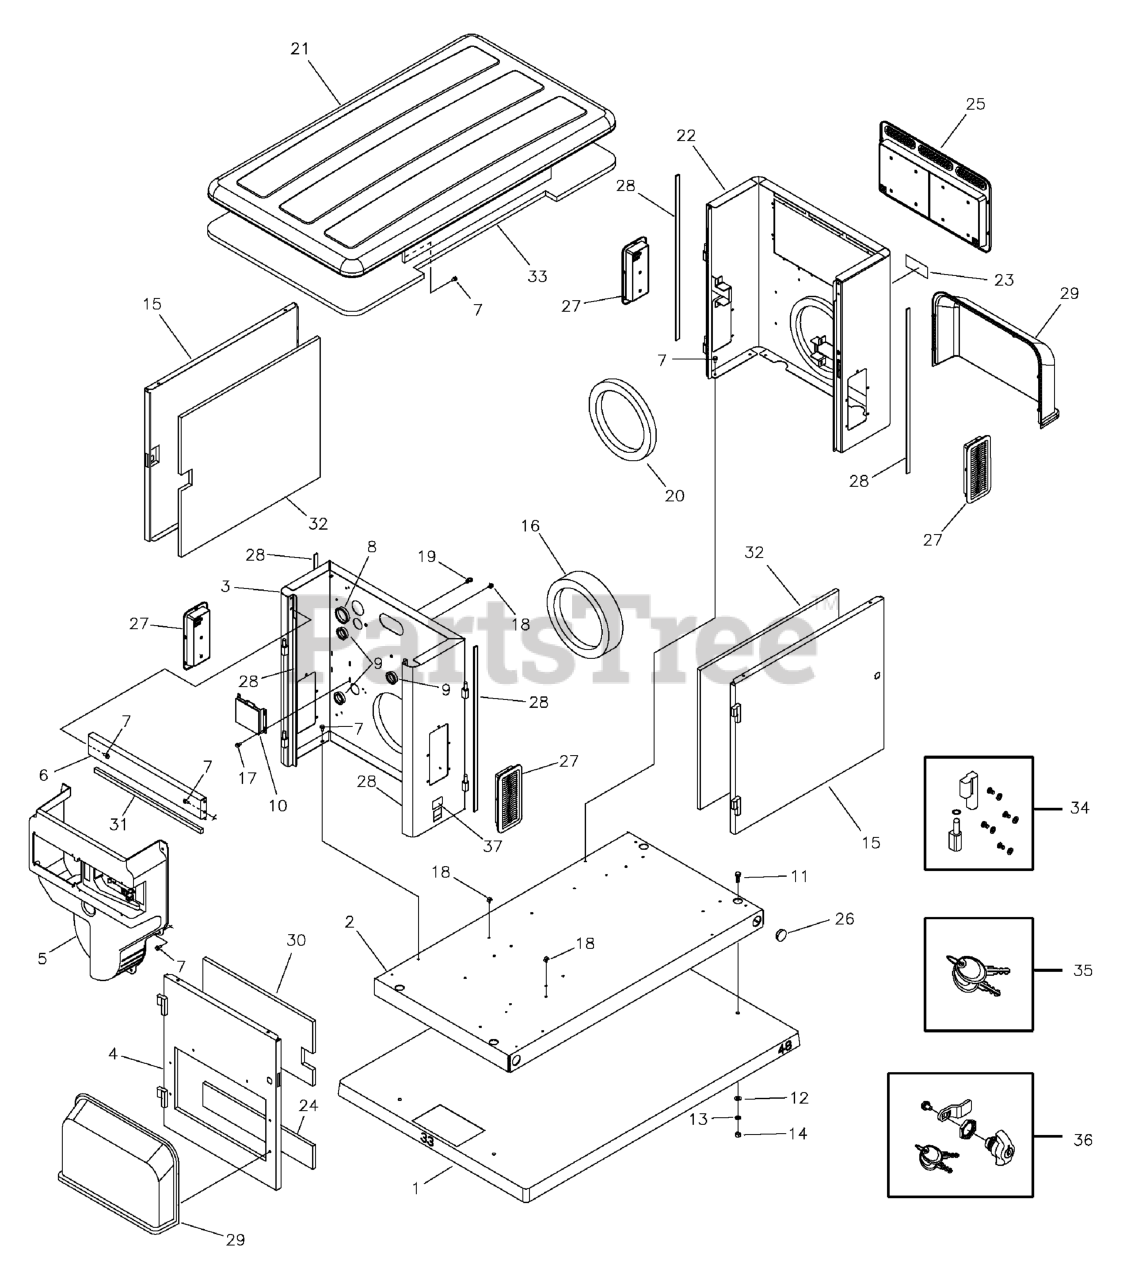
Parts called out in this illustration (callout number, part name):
1	PAD, Mounting w/ Holes
2	BASE, Mounting
3	BULKHEAD, Engine
4	ASSEMBLY, Door, Engine End
7	BOLT
9	BUSHING, Snap, 1-1/2
10	REGULATOR, Voltage
11	*CAPSCREW, Hex Head, 3/8-16 x 1
12	*WASHER, Flat, 3/8-M10
13	*WASHER, Lock, 3/8
14	*NUT, 3/8-16
16	SEAL, Foam, Engine Air
18	MOUNT, Tie Wrap
20	SEAL, Foam, Alternator Inlet
22	BULKHEAD, Alternator
24	INSULATION, Engine Door, Bottom
25	ASSEMBLY, Vent, Exhaust
29	COVER, Air Intake, Engine
30	INSULATION, Engine Door, Top
